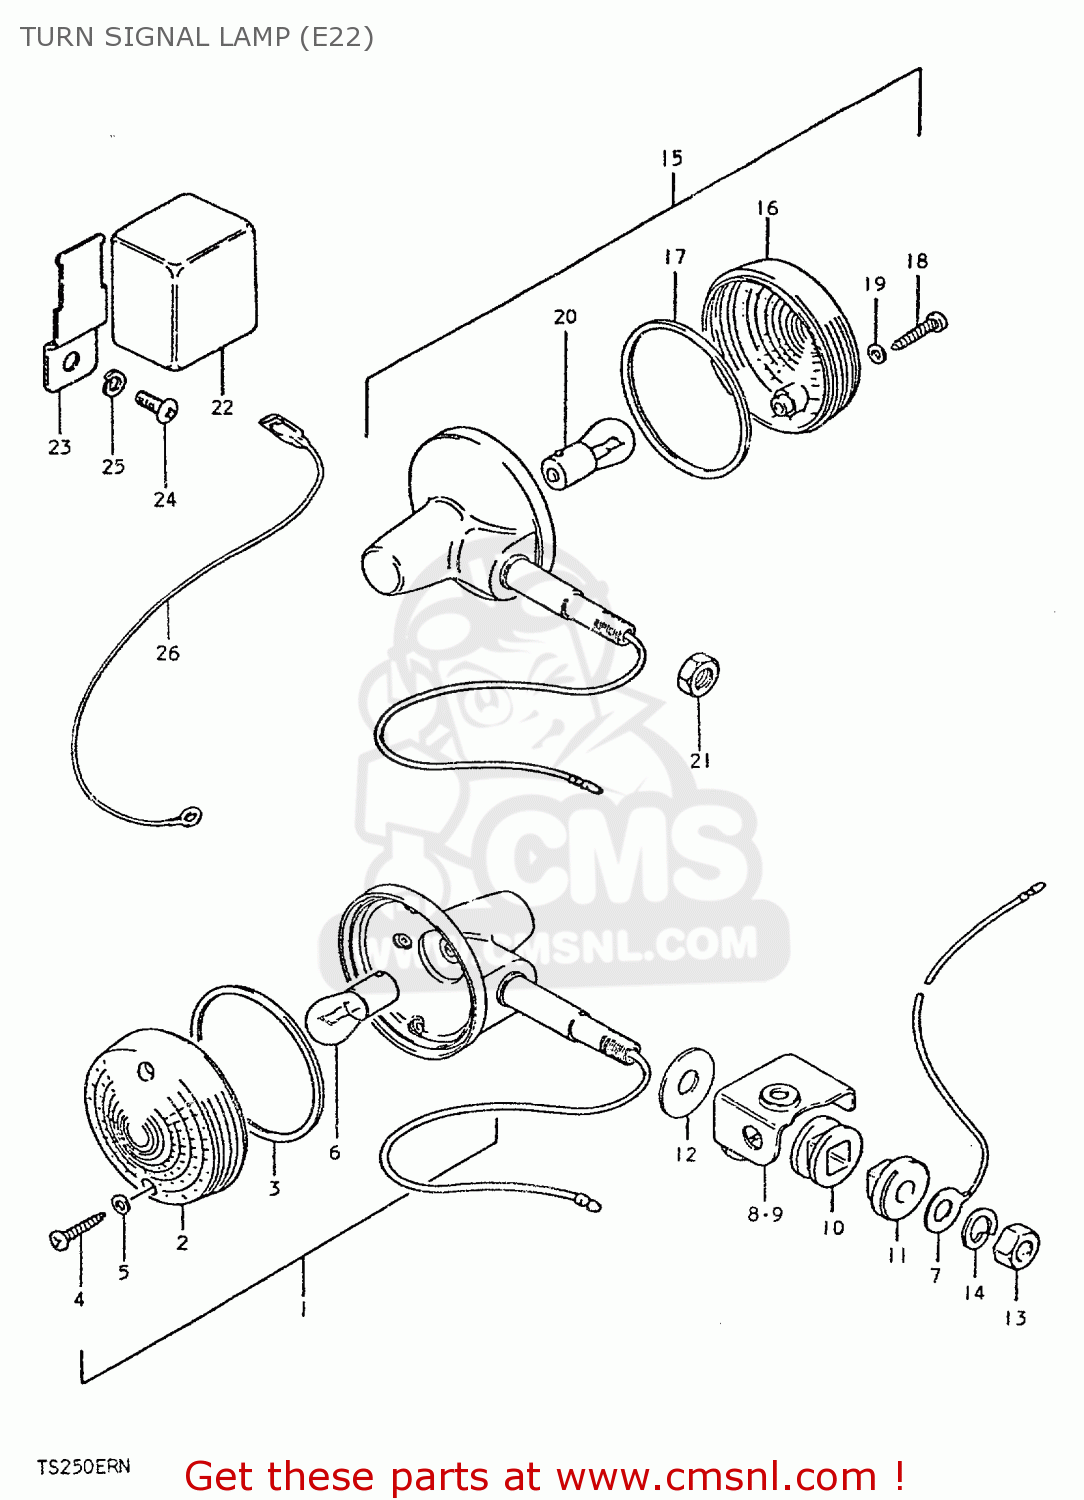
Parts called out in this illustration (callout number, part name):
1	LAMP, FRONT TURN SIGNAL
2	LENS
3	GASKET (NAS)
4	SCREW
5	GASKET (NAS)
6	BULB (6V,21W)
7	LEAD WIRE,EARTH
8	BRACKET, FRONT TURN SIGNAL LAMP RH
9	BRACKET, FRONT TURN SIGNAL LAMP LH
10	CUSHION
11	SPACER,RR TURNSIGNAL LAMP
12	WASHER (10.5X30X2.3)
13	NUT
14	LOCK WASHER
15	LAMP, REAR TURN SIGNAL
16	LENS
17	GASKET (NAS)
18	SCREW
19	GASKET (NAS)
20	BULB (6V,21W)
21	NUT
22	RELAY, TURN SIGNAL
23	BRACKET,TURN SIGNAL RELAY
24	SCREW 6X12
25	LOCK WASHER
26	LEAD WIRE, RELAY EARTH
